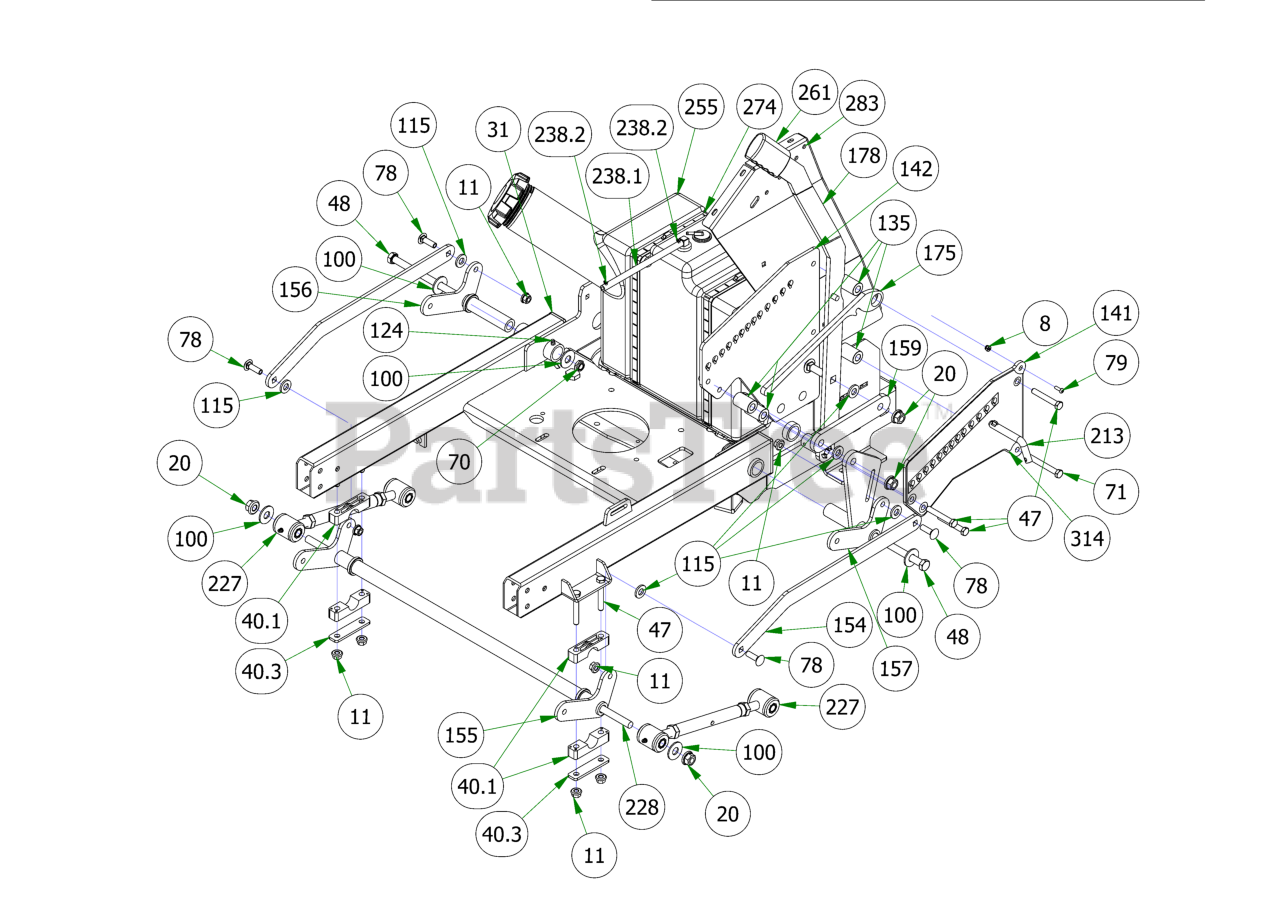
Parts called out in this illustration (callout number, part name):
8	10-24 NYLON INSERT LOCKNUT ZINC
9	3/8-16 NYLON INSERT LOCKNUT ZINC
11	3/8-16 NYLON INSERT FLANGE LOCKNUT (GR.F) ZINC
19	5/16-18 NYLON INSERT FLANGE LOCKNUT ZINC
20	1/2-13 NYLON INSERT FLANGE LOCKNUT ZINC
31	1 1/2 x 3 Frame Plug
40	Pillow Block Kit
40.1	Pillow Block MZ
40.3	Pillow Block Strap
42	1/2-13 X 1-1/2 CARRIAGE BOLT (GR.5) ZINC
47	3/8-16 X 2-1/2 HEX CAP SCREW (GR.5) ZINC
48	1/2-13 X 6 1/2 HEX CAP SCREW (GR.5) ZINC
59	1/2-13 x 1 3/4" GR5 Hex Bolt
70	1/2-13 NYLON INSERT JAM LOCKNUT ZINC
71	3/8-16 X 3 HEX CAP SCREW (GR.5) ZINC
73	5/16-18 X 1-1/4 CARRIAGE BOLT ZINC
78	3/8-16 X 1-1/4 CARRIAGE BOLT ZINC
79	10-24 X 5/8 BUTTON SOCKET CAP SCREW 18-8 STAINLESS STEEL
100	1/2 F/W USS (1-3/8" OD) ZINCC
115	.505 ID X 1.000 OD X .125 THICK FLAT WASHER NYLON
116	Revolt Cotter Pin for 7/8" to 1" shank
124	1/4 DRIVE-TYPE STRAIGHT GREASE FITTING (NO BALL) ZINC YELLOW
135	.502 ID X .750 OD X 1.500 Long Spacer
141	Outer Adjustment Plate 2019 Stand On
142	Inner Adjustment Plate 2019 Stand On
154	Revolt Actuator Linkage - BLACK
155	Revolt Front Actuator Bar Weldment 2020 36" Black
156	Revolt Rear Actuator Bar Weldment RH 2020 36" Black
157	Revolt Rear Actuator Bar Weldment LH 2020 36" Black
159	Lever Secondary Linkage Revolt Black
175	2019 Stand On Deck Lever Lock
178	2020 36" Stand On Deck Lift Lever Welded Assembly
213	Height Adj Pin
227	2018 Maverick Turnbuckle (Top Link)
228	2020 36 Stand On Turnbuckle Rod
238	Revolt Fuel Line Assembly
238.1	1/4 Fuel Line
238.2	1/4 Fuel Hose Clamp
255	2019 REVOLT FUEL TANK
261	2019 Stand On Lift Grip
266	2020 36" Stand On Frame
274	2019 Stand On Gas Tank Strap
283	LH Podium Panel
314	2022 Revolt Deck Height Decal
